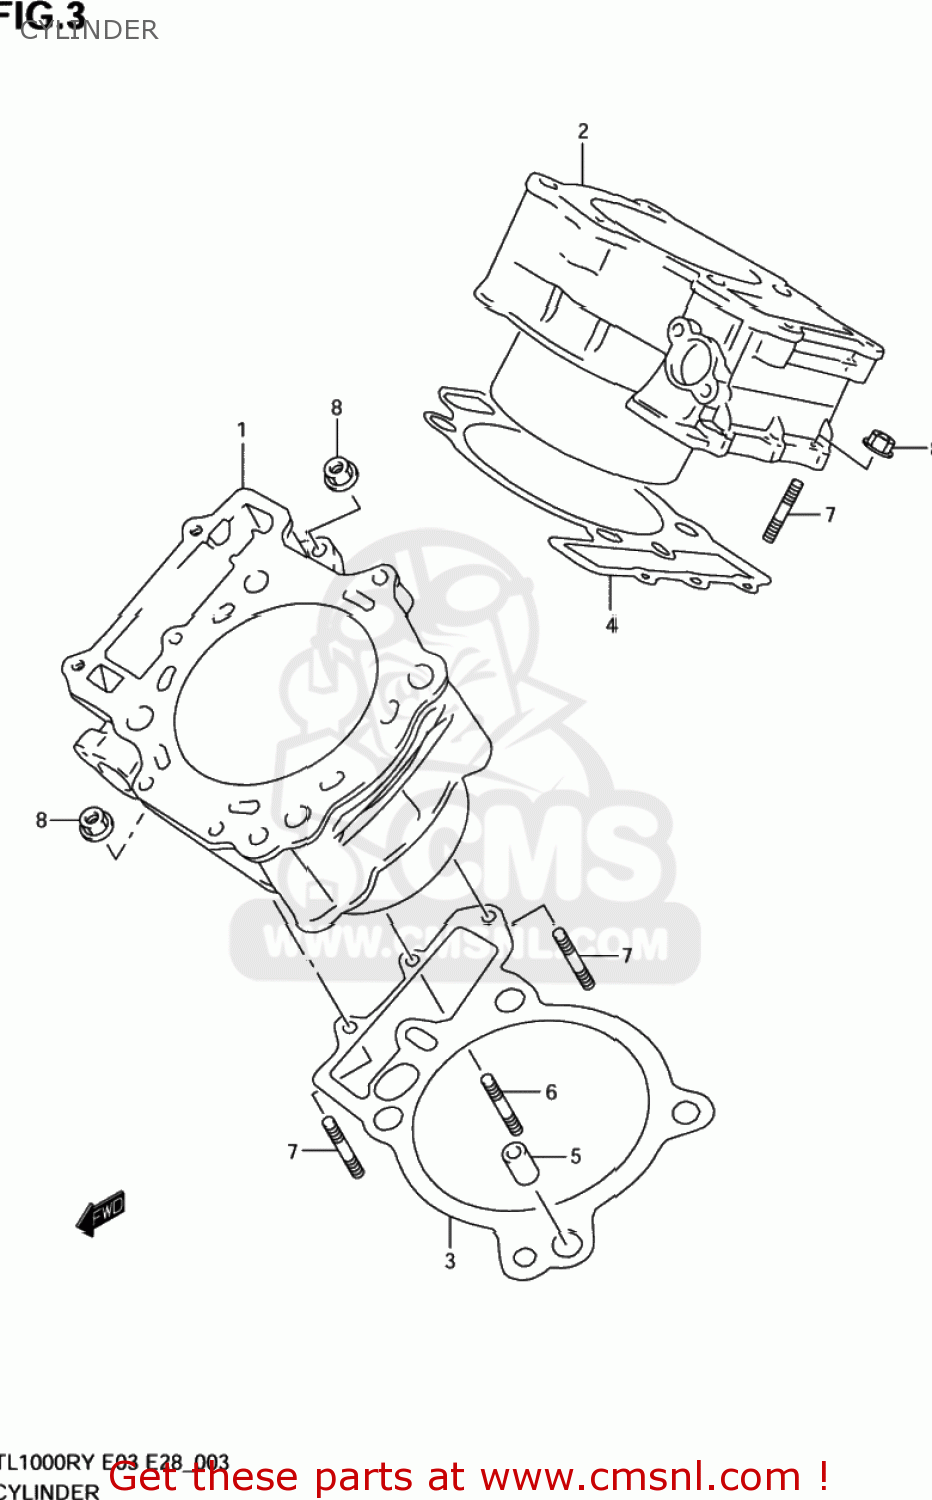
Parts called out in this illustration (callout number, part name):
1	CYLINDER,FR
2	CYLINDER,RR
3	GASKET,CYLINDER FR (NAS)
4	GASKET,CYLINDER RR (NAS)
5	PIN
6	STUD BOLT (L:20)
7	STUD,M6X1X32
8	NUT
